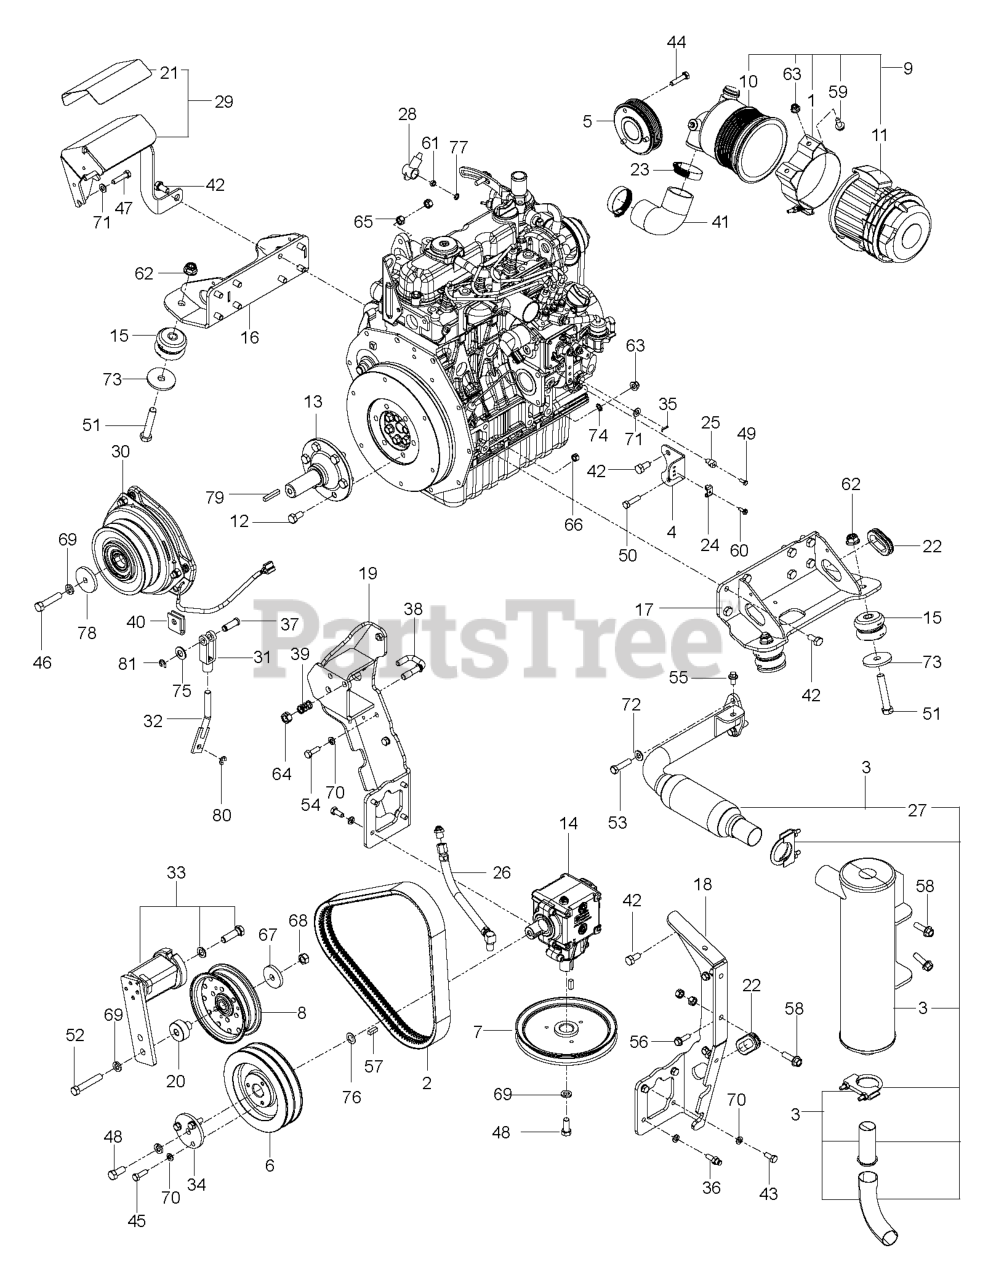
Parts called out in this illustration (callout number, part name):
1	MOUNTING BRACKET
2	BELT, CLUTCH
3	KIT.SPARK.ARRESTER
4	BRACKET, THROTTLE
5	PULLEY, CRANK
6	PULLEY, GEAR BOX
7	PULLEY, DRIVE, DECK
8	IDLER PULLEY
9	AIR FILTER ASSY - NON-TURBO
10	BODY - 90 DEG
11	PRECLEANER ASM
12	MUFFLER.DIESEL.KUBOTA
13	SHAFT, PILOT
14	GEAR BOX, 90 DEGREE
15	ISOLATOR, ENGINE
16	MOUNT, MOTOR, LT - BLK
17	MOUNT, MOTOR, RT - BLK
18	MOUNT, GEAR BOX, BLK
19	MOUNT, GEAR BOX, BLK
20	MOUNT, IDLER
21	SHIELD, HEAT BARRIER
24	CLAMP, CABLE
25	SWIVEL, THROTTLE
26	HOSE, VENT
27	PIPE, MANIFOLD, DIESEL
28	TERMINAL COVER-SM
29	SHIELD, HEAT
30	CLUTCH, OGURA, DIESEL
31	YOKE, CLEVIS
32	LINKAGE, ANTI-ROTATION
33	TENSIONER, LOVEJOY, SE27
34	PLATE, PULLEY
35	COTTER PIN 3/32 X 1/2
36	PIN, PIVOT
37	PIN, 7/16 CLEVIS
38	PIN, DETENT
39	SPRING, COMPRESSION
40	SPACER, RUBBER
41	HOSE, AIR INTAKE
42	HCS M10-1.25 X 20 GR 8.8 ZD
43	SCREW 5/16C X 1 HEX CAP
44	HCS MB 1.25 X 35 GR 8.8 ZD
45	HCS 5/16C X 1
46	HCS 7/16-20 X 2 G8 ZN
47	HTB M8-1.125 X 25MM
48	SCREW 7/16-20 X 1 HHB GR5
49	HCS #10-24 X 1/2
50	HCS 5/16C X 1 1/4
51	HCS 1/2C X 2 3/4
52	HCS 7/16-20 X 2-3/4
53	HCS 3/8C X 1 1/2
54	M8X1.25X25 HHB GR8.8
55	SCREW M8X1.25X16 HHB GR 8.8
56	5/16-18X1 TAP SCREW
57	KEY 1/4 SQ X 3/4
58	HHFS 3/8-16 X 1.25 GD 5
59	BOLT 5/16-18 X 3/4
60	SCREW #10 X 1/2 SELF TAPPING
61	NUT M6 X 1.0 HEX
62	NUT, 1/2-13 HEX FLG NYLOC ZD
63	5/16-18 NYLOC FLANGE NUT
64	NUT 7/16C CENTERLOCK
65	NUT 3/8C CENTERBLOCK
66	NUT 5/16C CENTERLOCK
67	NUT, 7/16-20 HEX NYLOC ZC
68	SPINDLE WASHER
69	WASHER 7/16 LOCK
70	WASHER.LOCK.HVY.HLCL.SPR.5/16
71	FLAT WASHER 5/16 SAE
72	WASHER 3/8 SAE FLAT
73	WASHER, HEAVY
74	WASHER 5/16 EXT STAR
75	WASH 1/2 X 1 SPRG STL & NEOP
76	WASHER .515 X .874 X .031
77	WASHER 1/4 INT TOOTH
78	BLADE WASHER
79	KEY 1/4 SQ X 1-1/2
80	E RING 3/8"
81	RING, E, 7/16
